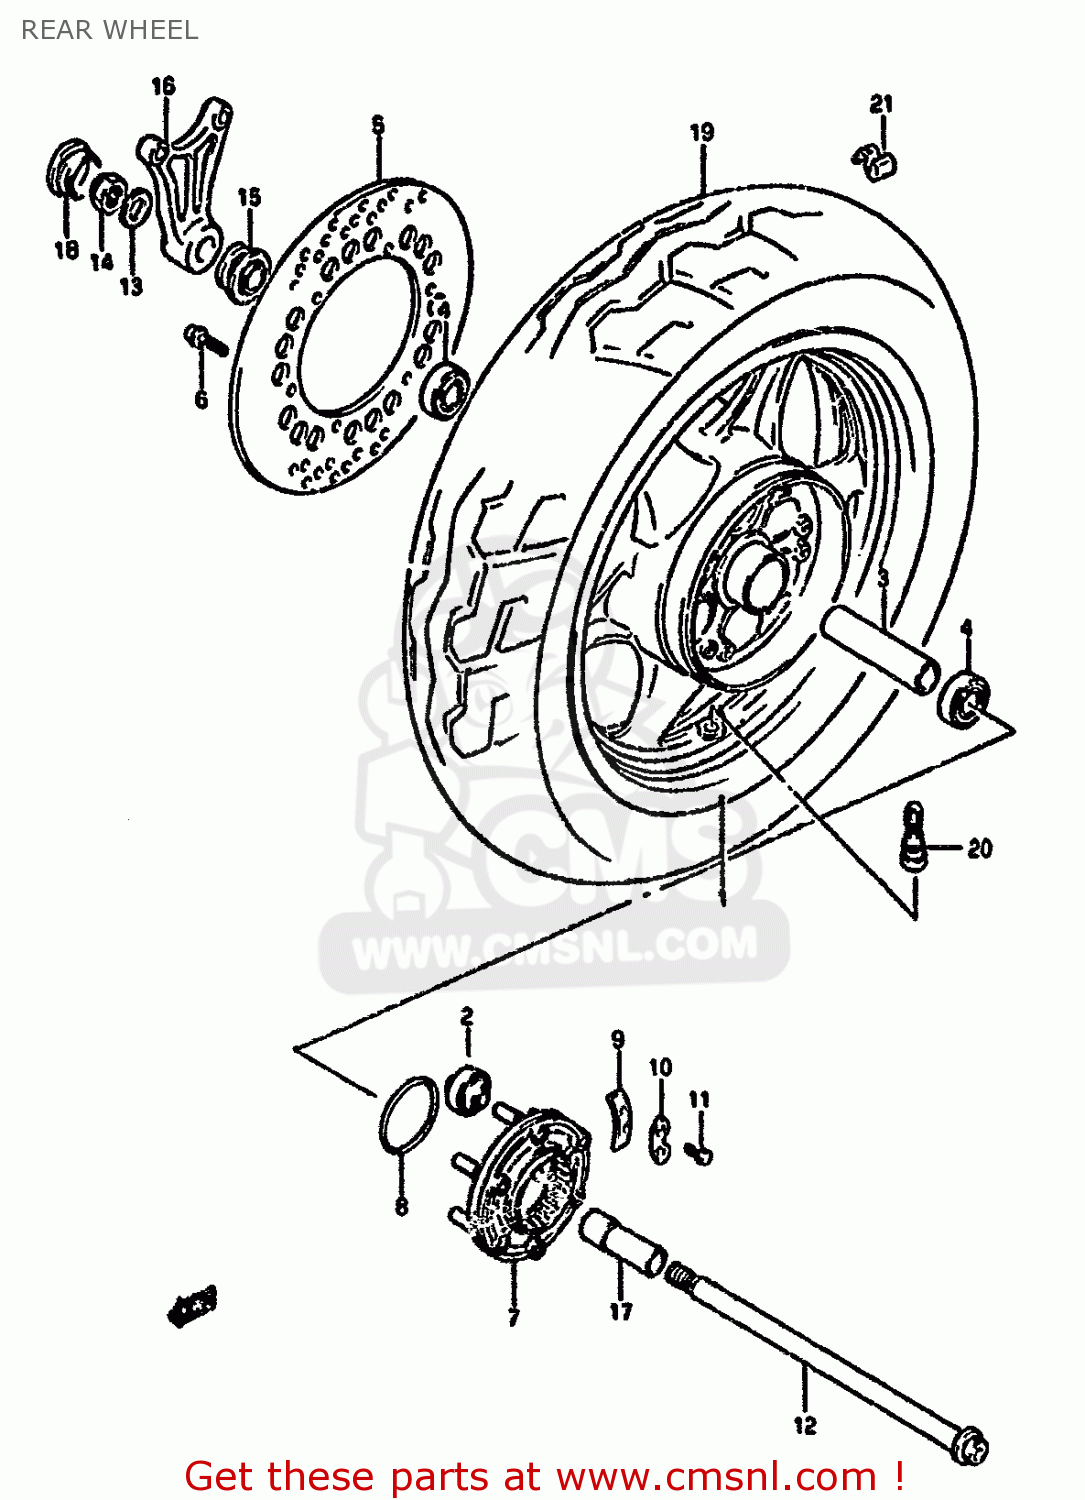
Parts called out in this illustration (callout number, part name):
1	WHEEL SET,REAR (17XMT4.50)
2	BUSH
3	SPACER(20.8X27.2X124)
4	BEARING(20X47X14)
5	DISC,RR BRAKE
6	BOLT
7	JOINT ASSY,RR HUB DRIVEN
8	O RING(D:2.1,ID:65)
9	WASHER,THRUST(T:1.6)
10	WASHER
11	BOLT(6X16)
12	AXLE,RR
13	WASHER
14	NUT
15	SPACER,RR AXLE,R
16	BRACKET,REAR CALIPER
17	SPACER,REAR AXLE,LEFT
18	CAP,RR AXLE,R
19	TIRE,REAR (160/70 VB17 V240) (METZELER)
20	VALVE ASSEMBLY,WHEEL,TR412
21	BALANCER,WHEEL
